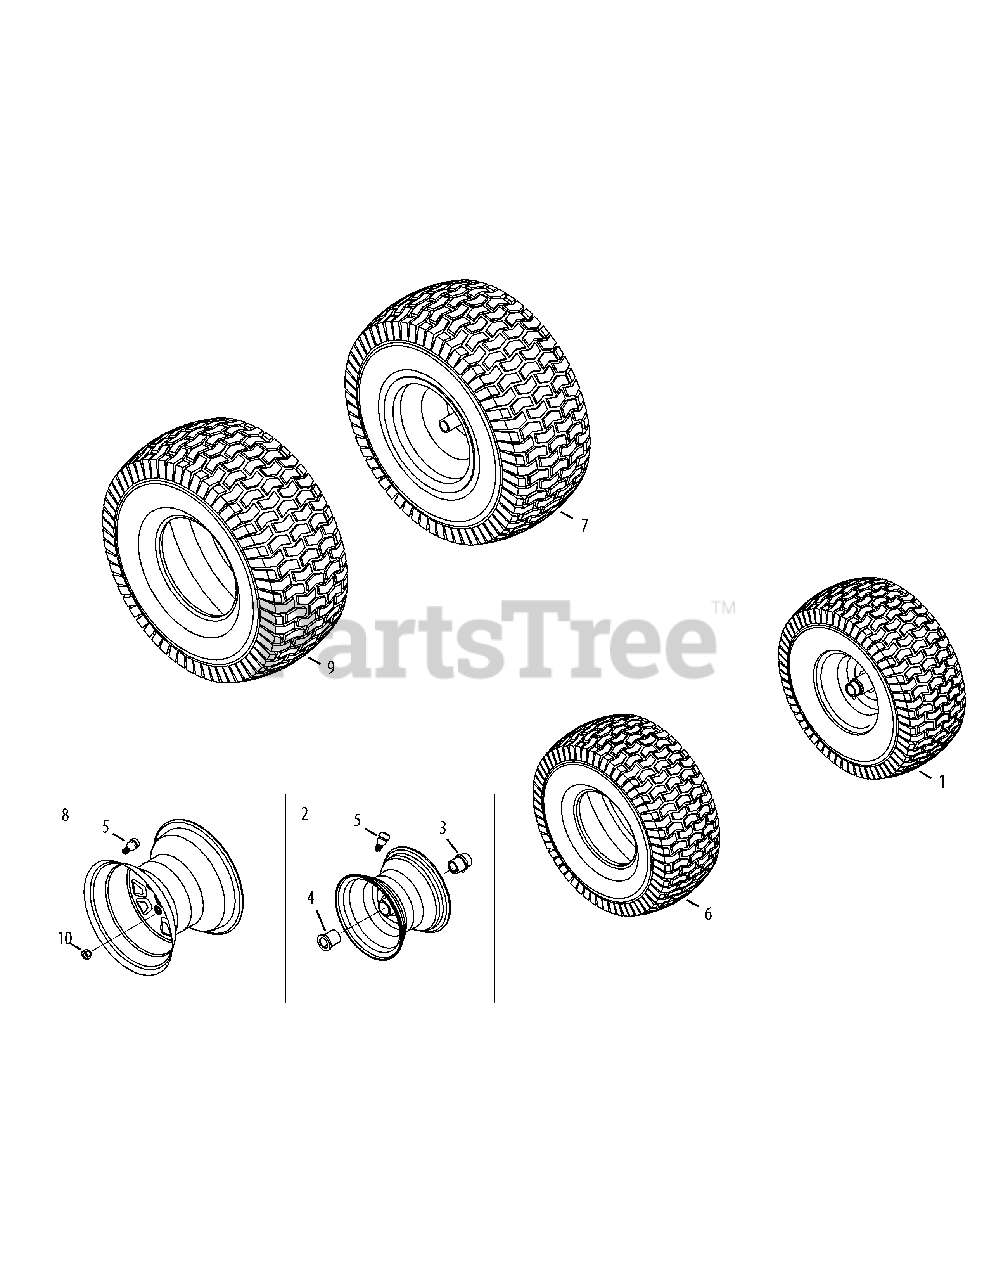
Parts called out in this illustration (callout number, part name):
1	Wheel Ass’y, Complete, 16 x 6 x 5.8
2	Rim Ass’y, 8.0 x 5.3, w/ Flange Bearings
3	Bearing, Flange, .760 ID w/ Fitting
4	Bearing, Flange, .760 x 1.00 x 1.20
5	Valve, Tubeless Air
6	Tire, 16 x 6.5 x 8 Sq Shoulder
7	Wheel, Complete, 23 x 10.5 x 12
8	Rim Ass’y, 12.0 x 7.0
9	Tire, 23 x 10.5 x 12 Sq Shoulder
10	Nut, Lug, 7/16-14
